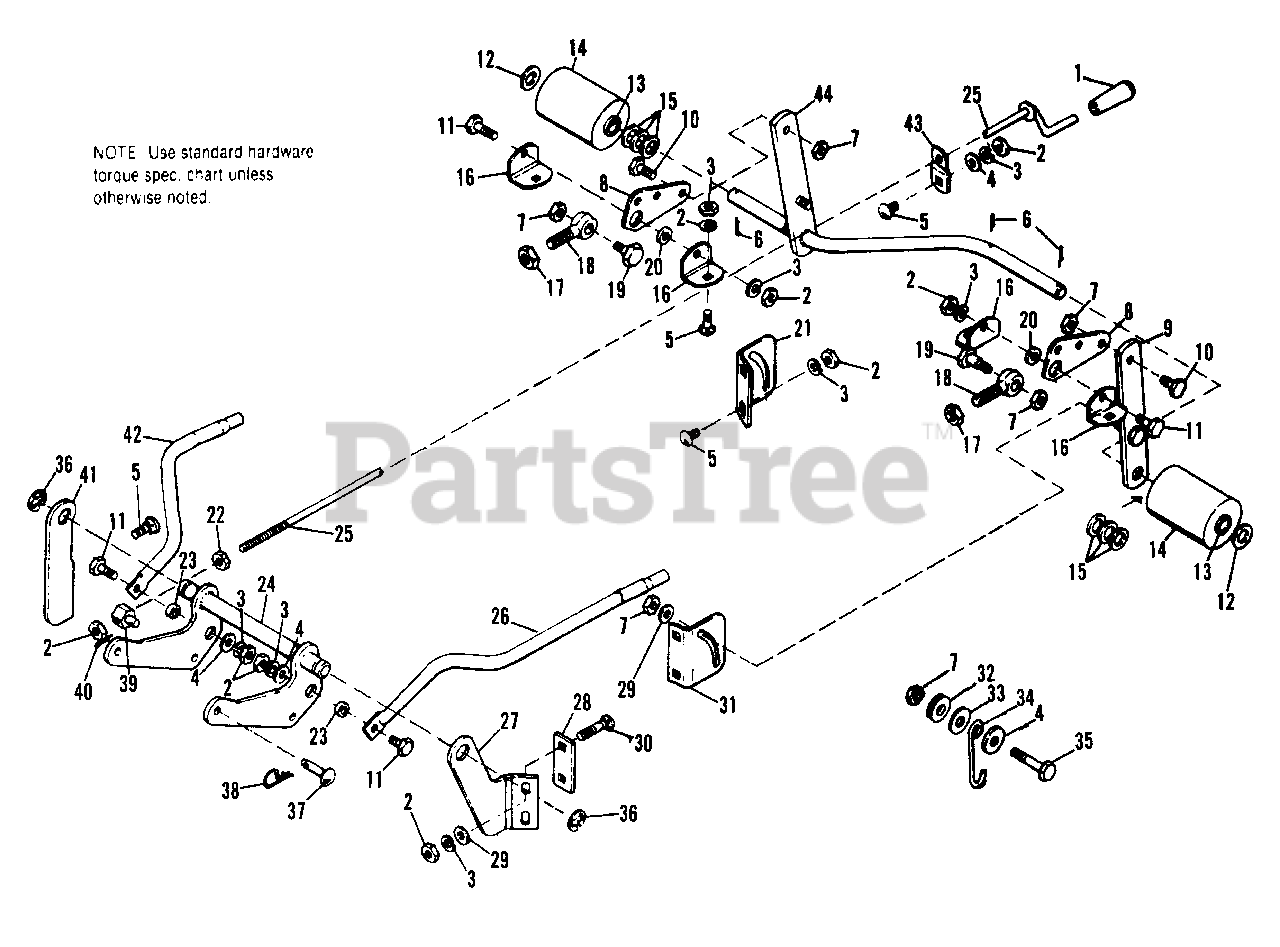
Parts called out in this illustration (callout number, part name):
2	NUT, Hex, Full, 3/8-16
3	LOCKWASHER, 3/8
4	WASHER, Plain, 3/8
5	BOLT, Carriage, 3/8-16 x 3/4
6	PIN, Cotter, 3/16 x 1
7	LOCKNUT, Hex, 3/8-16
8	LEVER, Rear
9	BAR ASSY., Roller
10	CAPSCREW, Hex Hd., 3/8-16 x 7/8
11	CAPSCREW, Hex Hd., 3/8-16 x 1
14	ROLLER ASSY.
16	BRACKET, Pivot
17	LOCKNUT, Hex, Jam, 1/2-20
19	BOLT, Shoulder
21	BRACKET, Roller, R.H.
22	LOCKNUT, Hex, Jam, 3/8-16
24	HITCH ASSY., Mower
25	SCREW ASSY., Adjusting
26	ARM, Adjusting, L.H.
27	BRACKET, Front, L.H.
29	WASHER, Plain, 5/16
30	BOLT, Carriage, 3/8-16 x 1-1/4
31	BRACKET, Roller, L.H.
32	LOCKWASHER, Double, 3/8
33	WASHER, Nylon
34	LIFT, Mower
35	CAPSCREW, Hex Hd., 3/8-16 x 1-1/4
36	RING, Retaining
38	CLIP, Spring
40	PIN, Cotter, 3/32 x 3/4
41	BRACKET, Front, R.H.
42	ARM, Adjusting, R.H.
43	BRACKET, Screw, Adjusting
44	SHAFT ASSY., Roller Bar
